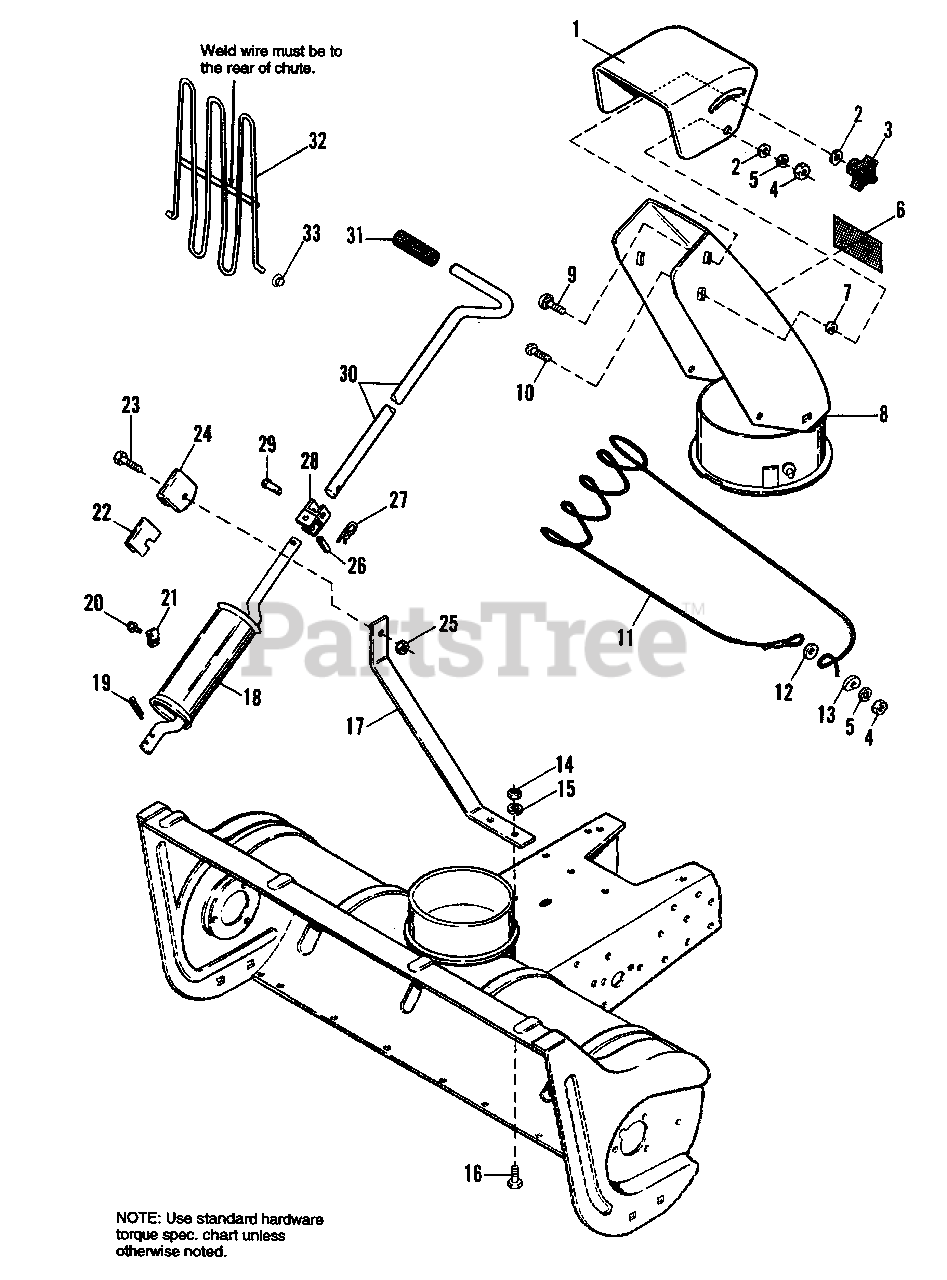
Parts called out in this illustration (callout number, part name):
1	DEFLECTOR
2	WASHER, 11/32 Std.
4	NUT, Hex, 5/16-18
5	WASHER, Spring Lock, 5/16
6	DECAL, Danger, Blower
8	CHUTE ASSY.
9	BOLT, Carriage, 5/16-18 x 1
10	SCREW, Truss, Phil. Hd., 5/16-18 x 3/4
11	CABLE ASSY.
12	WASHER, 5/16 Std.
13	WASHER, Cup
14	NUT, Hex, 3/8-16
15	LOCKWASHER, 3/8 Std.
16	CAPSCREW, Hex Hd., 3/8-16 x 1
17	BRACE, Handle
18	SPOUT CONTROL ASSY.
19	PIN, Cotter, 3/32 x 3/4
20	SCREW, Hex, Taptite, 1/4 x 3/8
23	CAPSCREW, Hex Hd, 5/16-18 x 1-1/2
25	NUT, Hex, Lock, 5/16-18
26	PIN, Spring, 3/16 x 3/4
27	RN, Hair
28	"U" JOINT ASSY.
29	PIN
30	HANDLE, Pivot
31	GRIP, Handle
32	GUARD ASSY., Chute
